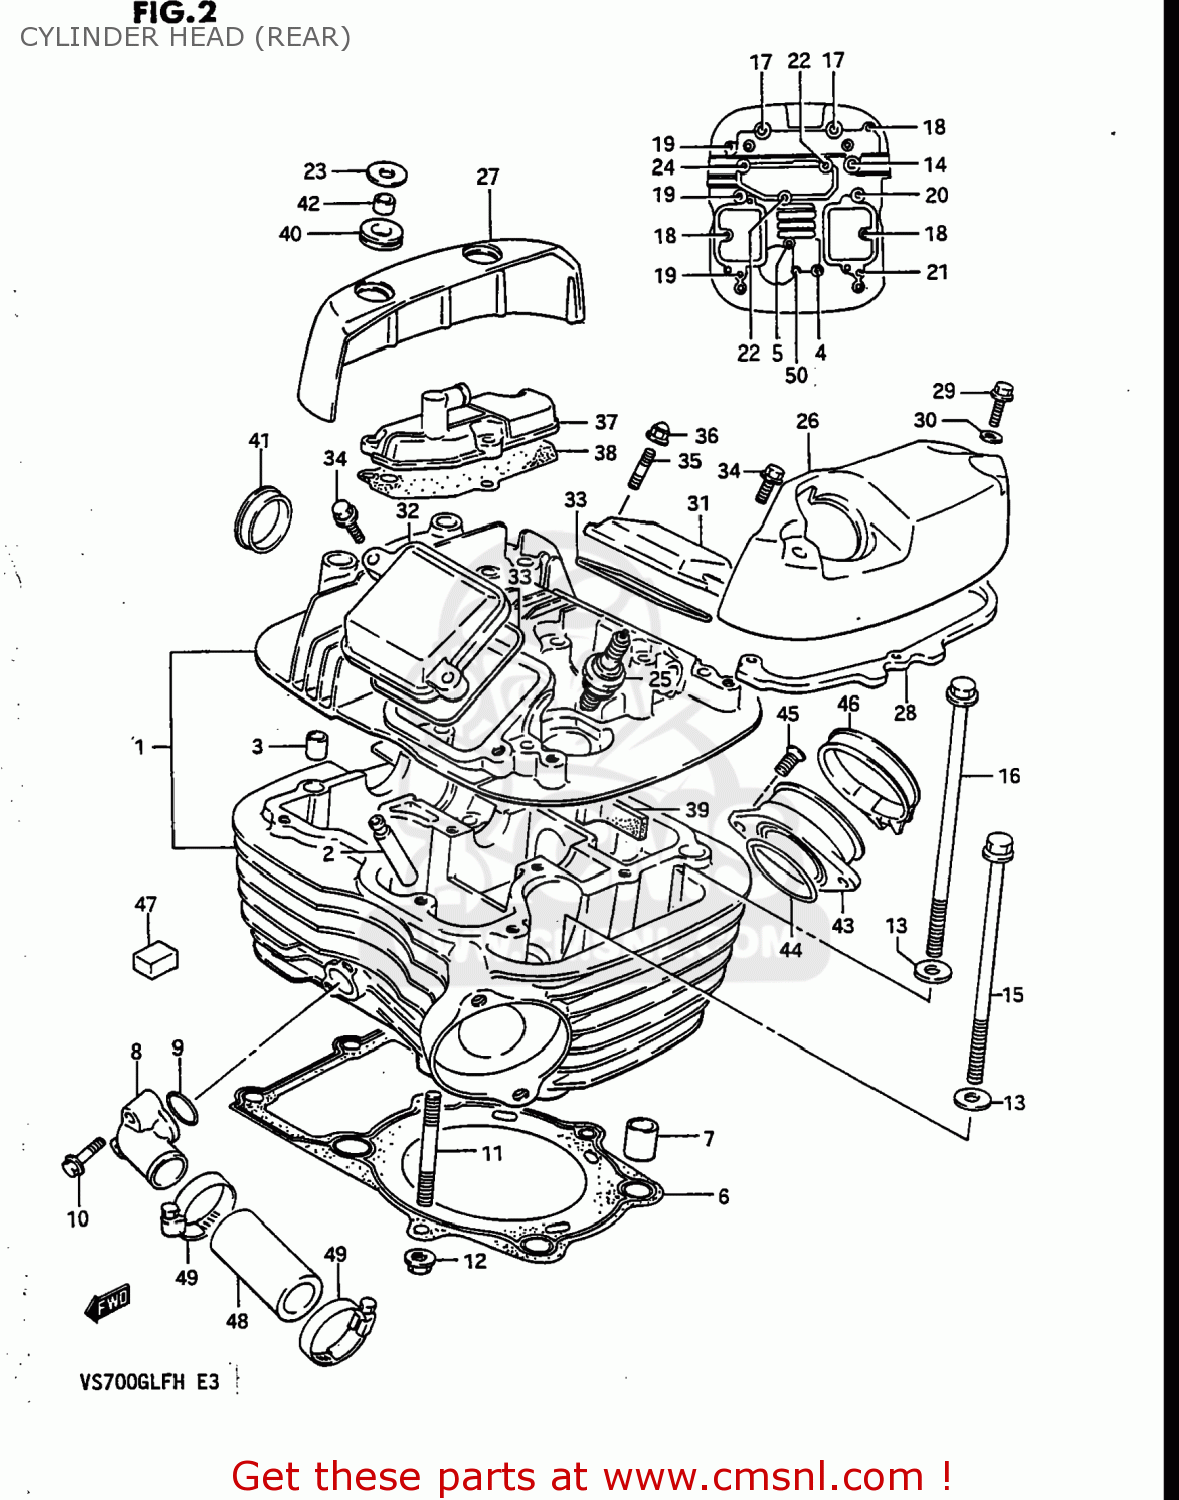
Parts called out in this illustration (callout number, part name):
1	HEAD ASSEMBLY,CYLINDER,REAR
2	GUIDE,VALVE
3	PIN(11X14)
4	BOLT(6X50)
5	BOLT(6X55)
6	GASKET,CYLINDER HEAD RR (MCA)
7	PIN
8	UNION,CYLINDER HEAD WATER
9	O RING(D:2.4,ID:17.8)
10	BOLT
11	BOLT,STUD
12	NUT
13	WASHER(10.5X22X2.3)
14	BOLT(8X140)
15	BOLT(10X155)
16	BOLT(10X165)
17	BOLT(8X245)
18	BOLT
19	BOLT
20	BOLT
21	BOLT
22	BOLT(6X55)
23	WASHER (8.2X24X1.6)
24	BOLT,REAR
25	SPARK PLUG DP8EA-9
26	CAP,CYLINDER HEAD COVER RR,L
27	CAP,CYLINDER HEAD COVER RR,R
28	CUSHION,RR,L CAP
29	BOLT
30	WASHER
31	CAP,INSPECTION
32	CAP,INSPECTION,EXHAUST
33	GASKET,INSPECTION CAP (NAS)
34	BOLT (6X20)
35	STUD 6X16
36	MOER
37	COVER,BREATHER
38	GASKET,BREATHER COVER (NAS)
39	PLATE,HEAD COVER RR
40	CUSHION
41	PLUG
42	BUSH
43	PIPE,INTAKE
44	O-RING (D:2.4 ID:39.7)
45	SCREW
46	CLAMP,PIPE
47	PAD
48	HOSE,CYLINDER HEAD JOINT
49	CLAMP
50	BOLT
